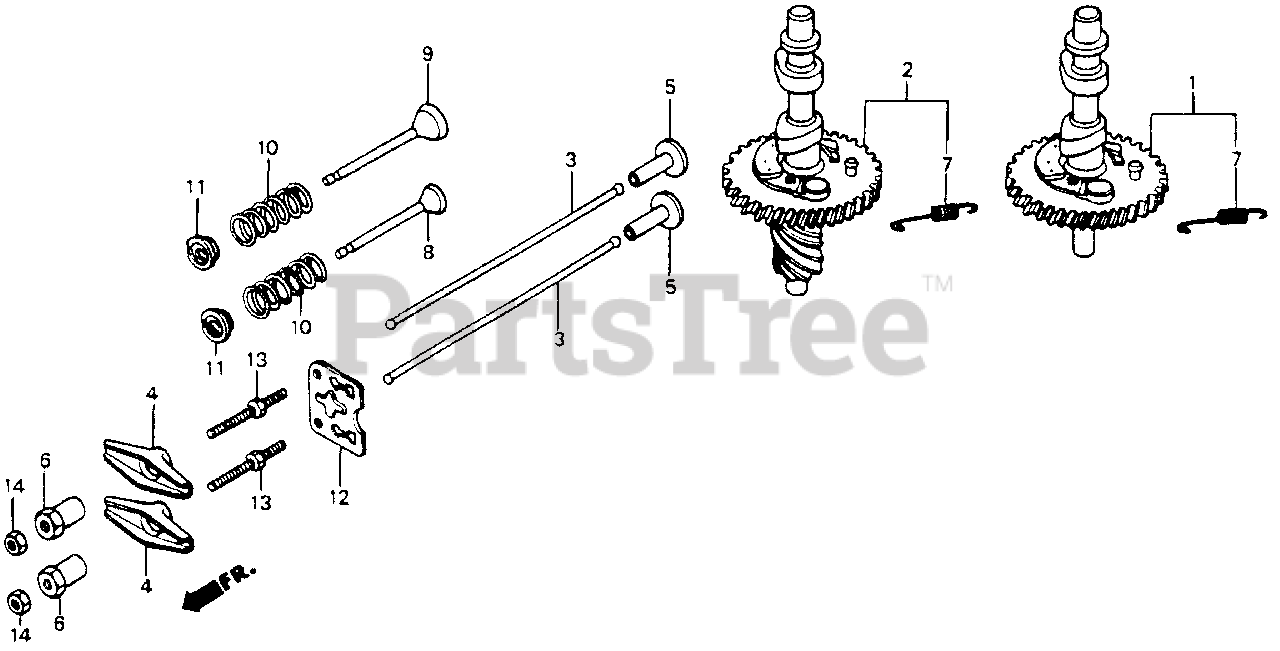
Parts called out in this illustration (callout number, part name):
2	CAMSHAFT ASSY.
3	ROD, PUSH
4	ARM, VALVE ROCKER
5	LIFTER, VALVE
6	PIVOT, ROCKER ARM
7	SPRING, WEIGHT RETURN
8	VALVE, IN.
9	VALVE, EX.
10	SPRING, VALVE
11	RETAINER, IN. VALVE SPRING
12	PLATE, PUSH ROD GUIDE
13	BOLT, PIVOT
13	BOLT, PIVOT (8MM)
14	NUT, PIVOT ADJ.
